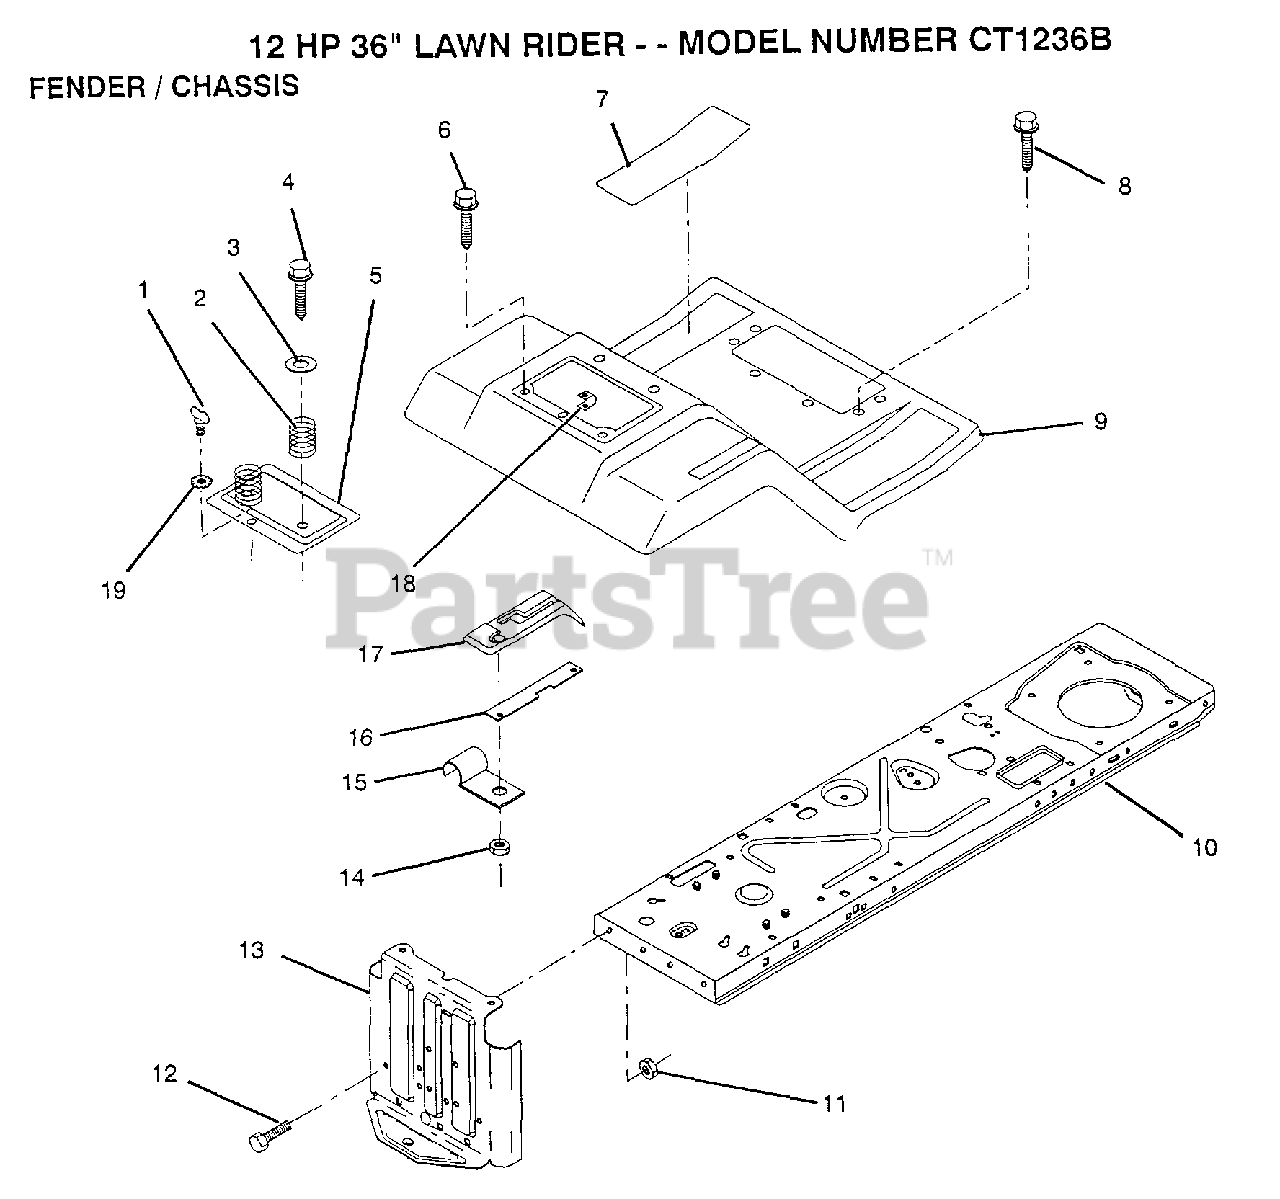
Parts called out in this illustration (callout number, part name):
1	STUD.1/4.TURN
2	SPRING COMPRESSIO
3	WASHER
4	SCREW
5	"DOOR,FENDER T"
6	SCREW LT
7	PAD FOOTREST
8	SCREW
9	"FENDER,FOOTREST T"
10	FRAME ASS'Y
12	BOLT
13	DRAWBAR
14	NUT
15	"CLIP,INSULATOR"
16	"SHIFT LOCK, BAR"
18	RECEPTACLE LT
19	RETAINER LT
